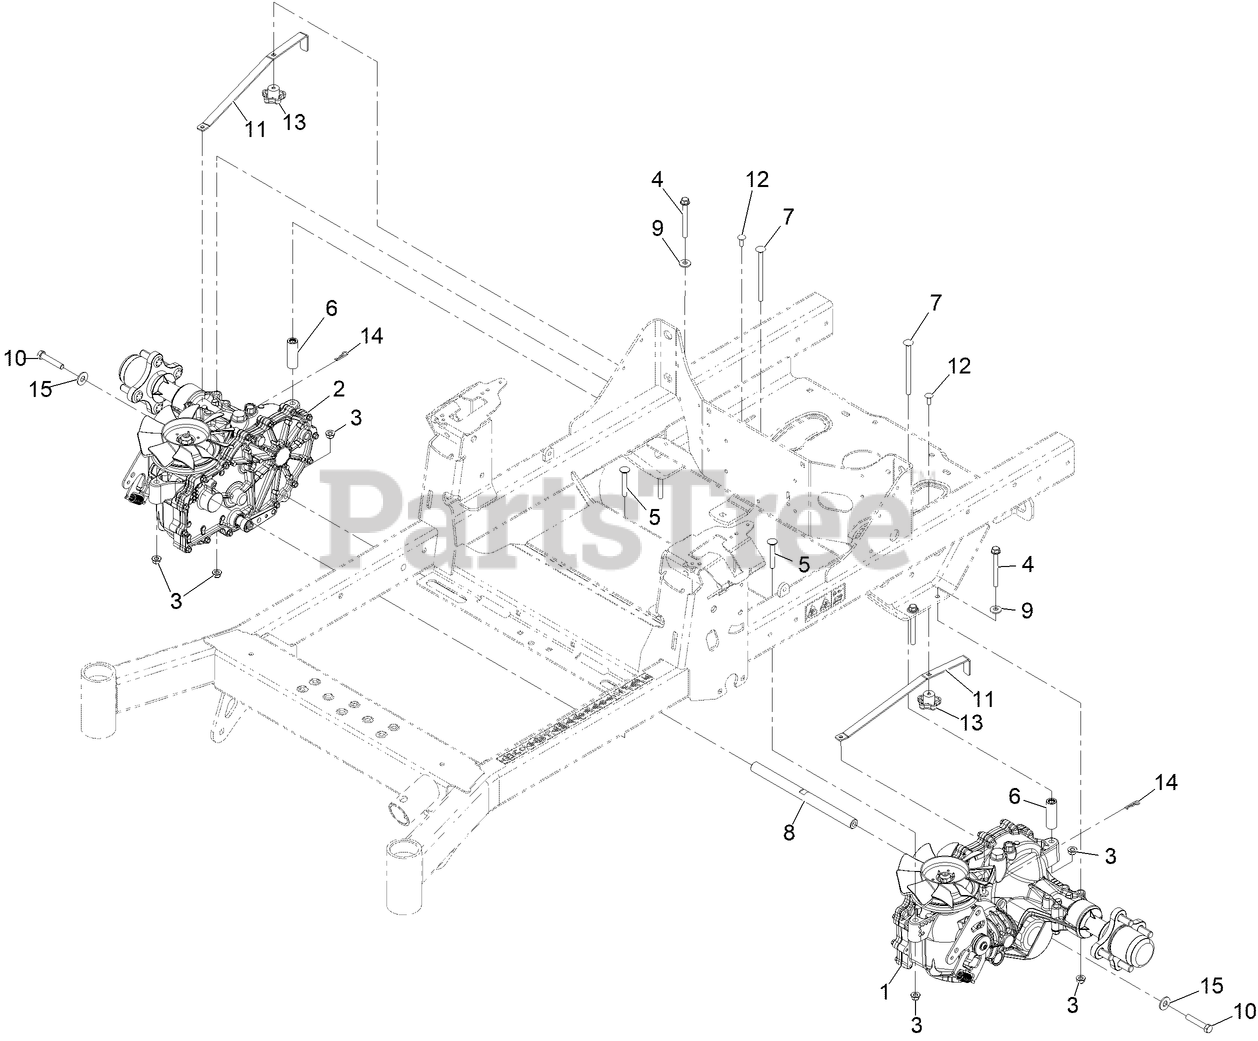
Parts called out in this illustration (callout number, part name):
1	TRANSAXLE ASM
2	TRANSAXLE ASM
3	NUT-HF, NI
4	SCREW-HHF
5	BOLT-CARR
6	SPACER, HYDRO
7	Bolt-Carriage 5/16-18 X 1 1/4
8	SHAFT-SPACER
9	WASHER-SPRING
10	SCREW-HH W/LOCTITE
11	ARM-BYPASS, HYDRO
12	BOLT-CARR
13	KNOB-HANDLE
14	PIN-COTTER
15	WASHER-FLAT
